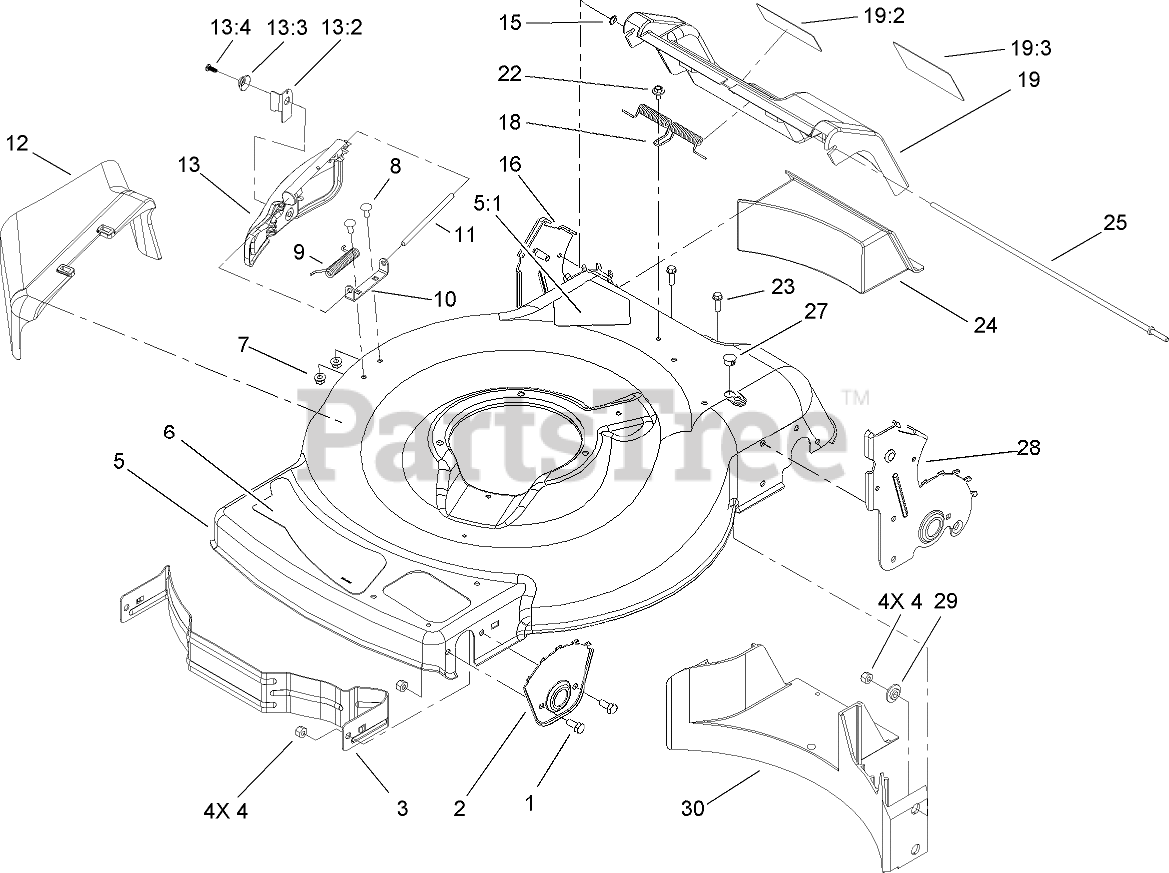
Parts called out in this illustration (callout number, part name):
1	SCREW-HH
2	Plate-HOC, Front
3	Baffle-Front
4	NUT-LOCK, NI
5	HOUSING
5:1	DECAL-DANGER
6	Decal-Deck
7	NUT-HHF
8	SCREW-CARR
9	SPRING-TORSION
10	BRACKET-COVER
11	ROD-COVER
12	CHUTE-DISCHARGE, SIDE
13	DISCHARGE DOOR ASM
13:2	LATCH-DOOR
13:3	CAP-DOOR
13:4	SCREW-PLASTITE
15	NUT-PUSH
16	RH REAR HOC PLATE ASM
18	Spring-Door, Rear
19	REAR DOOR ASM
19:2	DECAL-WARNING
19:3	DECAL-WARNING
22	SCREW AND WASHER ASM
23	SCREW-HWH
24	Plug-Discharge, Rear
25	Rod-Pivot, Rear Door
27	Plug-Dome
28	LH REAR HOC PLATE ASM
29	Washer-Stepped
30	Baffle-Rear
